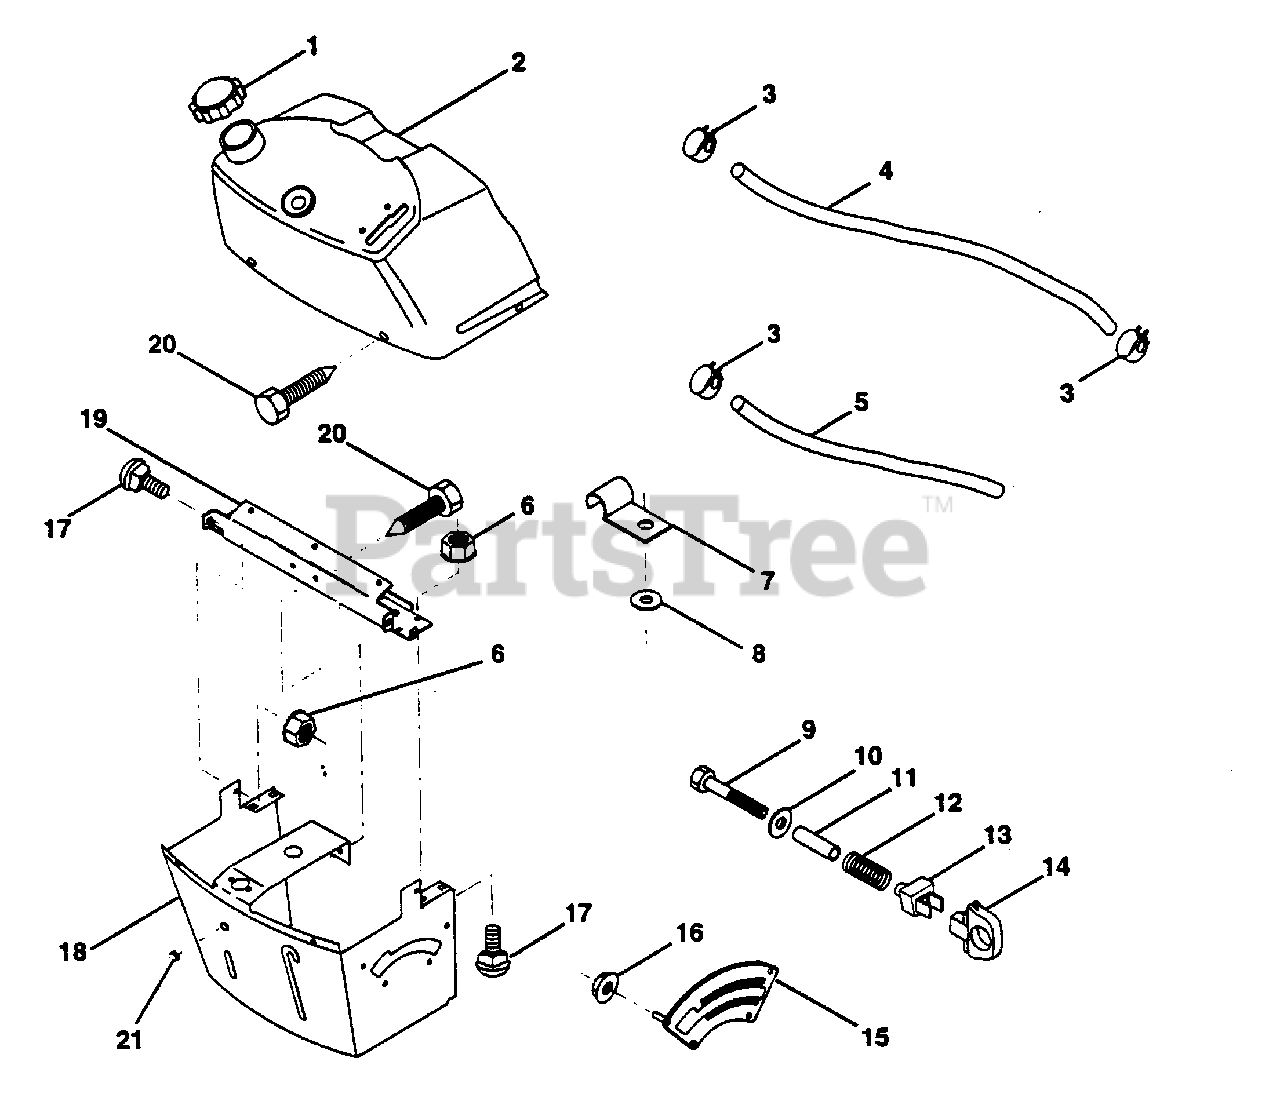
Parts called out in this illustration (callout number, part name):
1	Cap, Fuel (AYP part number)
2	Assembly, Dash & Fuel Tank (AYP part number)
3	Clamp, Hose (AYP part number)
4	Line, Fuel (AYP part number)
5	Line, Fuel (AYP part number)
6	Nut, Hex, Keps 1/4-20 (AYP part number)
7	Clip, Fuel Line (AYP part number)
8	Washer 9/32 x 3/4 x 16 Ga. (AYP part number)
9	Bolt, Hex, Fin 1/4-20 x 1-3/4 (AYP part number)
10	Washer 11/32 x 11/16 x 16 Ga. (AYP part number)
11	Spacer, Split (AYP part number)
12	Spring (AYP part number)
13	Clip, Height Adjustment (AYP part number)
14	Knob, Height Stop (AYP part number)
15	Adjustment, Quadrant Height (AYP part number)
16	Nut, Self-Threading 3/16-18 (AYP part number)
17	Bolt, Carriage 1/4-20 x 1/2 Gr. 5 (AYP part number)
18	Support Assembly, Dash (AYP part number)
19	Brace, Cross (AYP part number)
20	Screw, Self-Tapping 1/4-20 x 1/2 (AYP part number)
21	Plug Dome Black (AYP part number)
